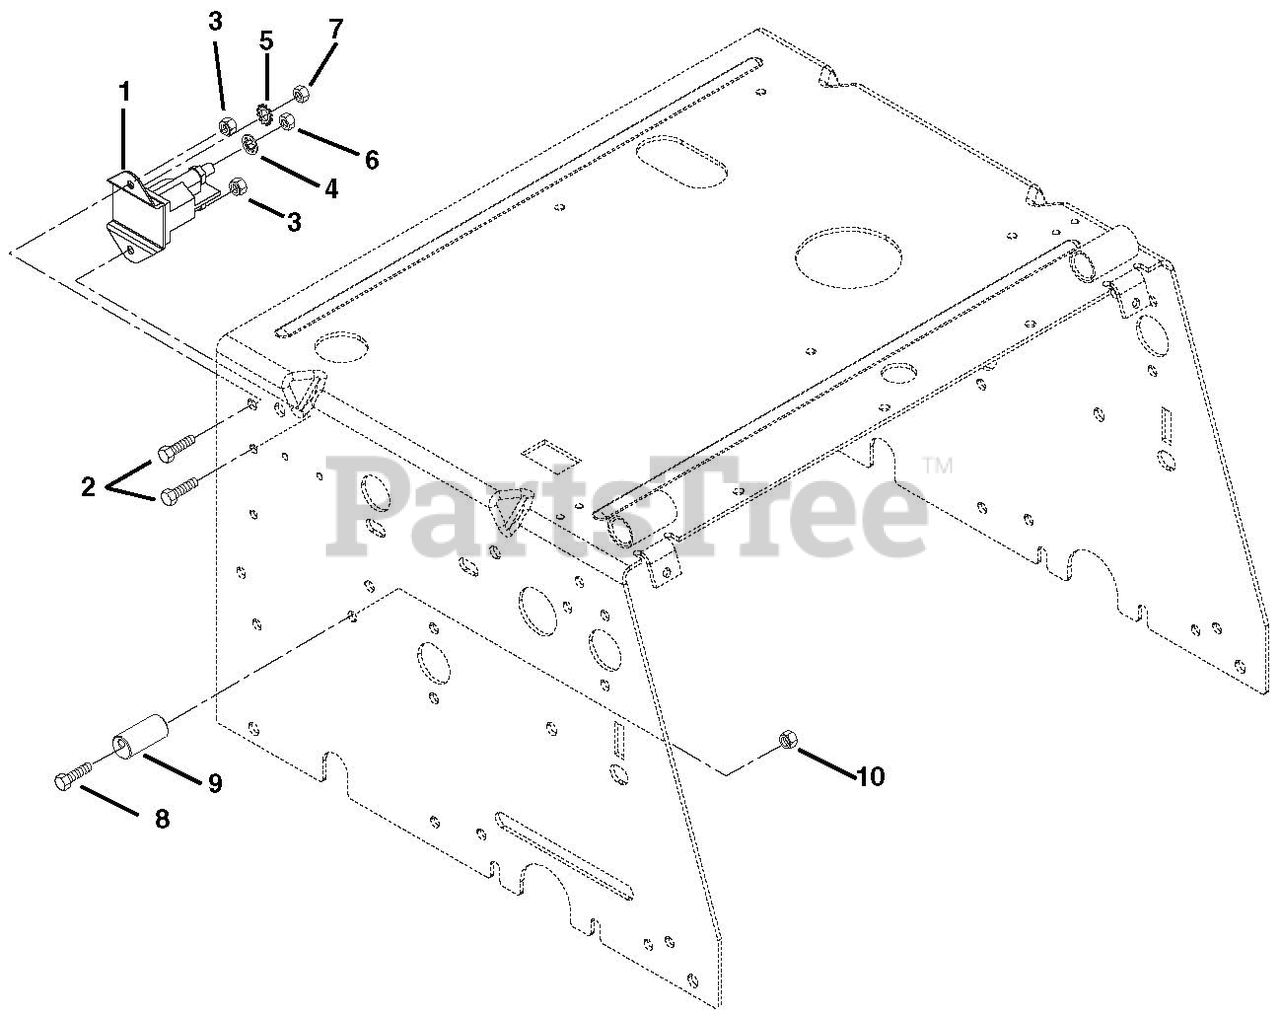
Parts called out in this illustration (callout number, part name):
1	SOLENOID
2	@BLT-HEX .25-20X.50 GR5 YWZC
3	@NUT-LK-CTR .25-20 YWZC
4	WSHR-LOCK INT .31 YWZC
5	@WSHR-LK-EXT.200X.402X.022YWZC
6	NUT-JAM .31-24 YWZC
7	NUT 10-32 YWZC
8	@BLT-HEX .31-18X2.75 GR5 YWZC
9	ECCENTRIC
10	@NUT-LK-NYL .312-18 YWZC
